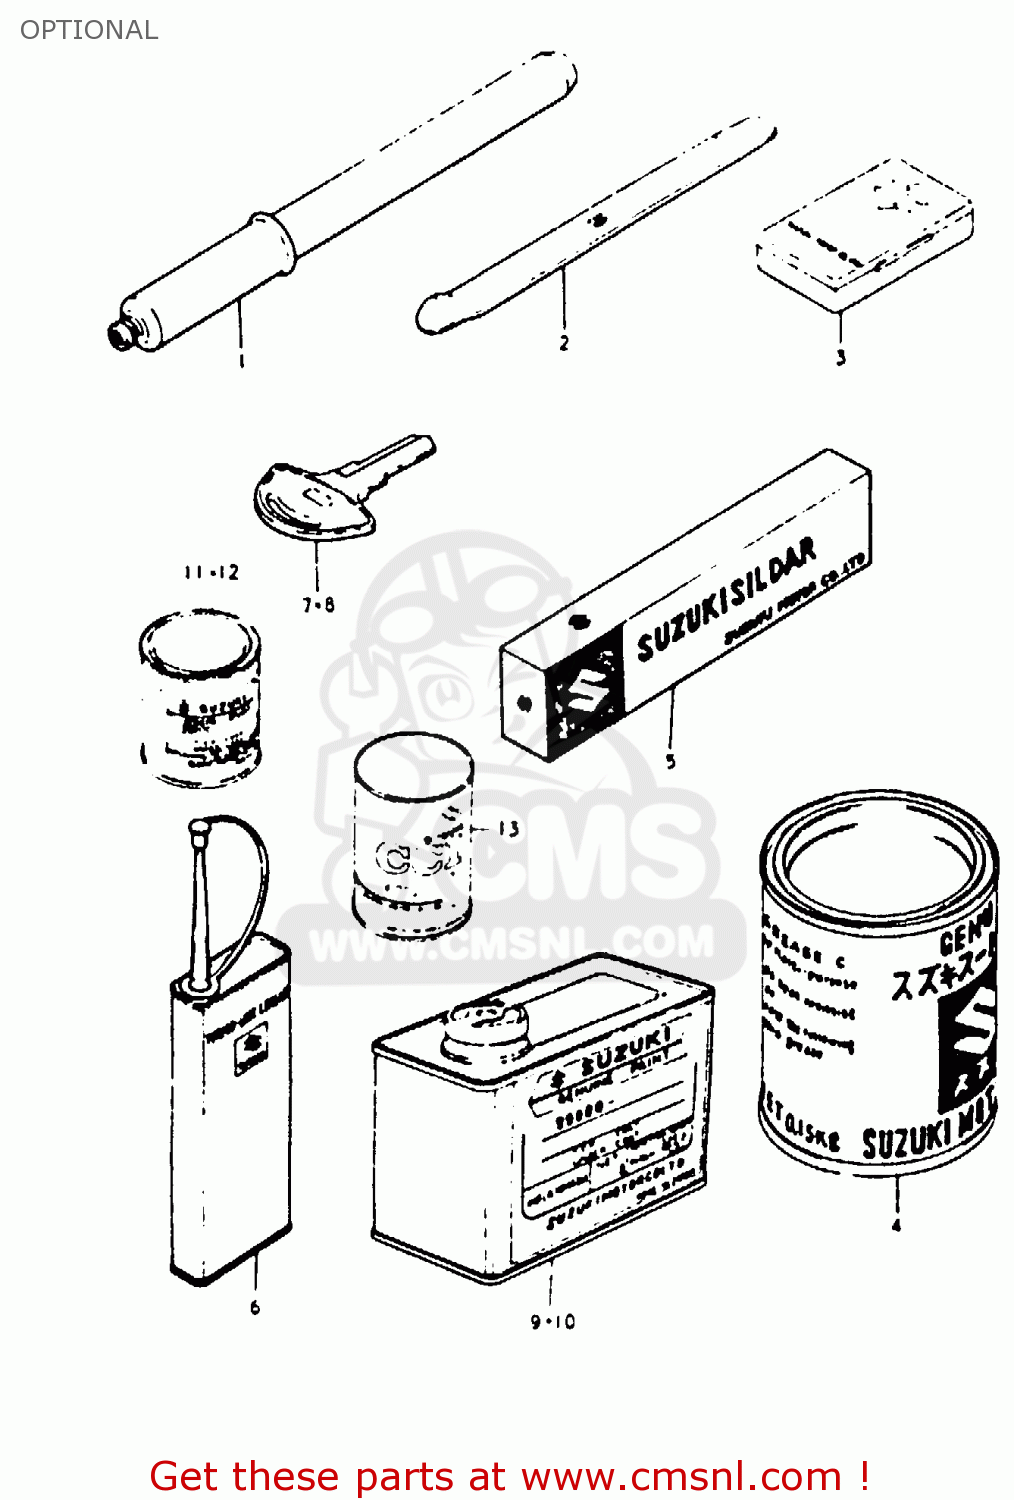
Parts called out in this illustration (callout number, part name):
1	INFLATOR, AIR
2	LEVER,TIRE
3	TUBE REPARING TOOL
4	GREASE(C)EP2 LITHIUM 150G
5	GASKET, LIQUID
6	THREAD LOCK NO.1401 CLEAR 200G
8	KEY,BLANK
9	PAINT (BLACK)
10	PAINT (MARBLE PURE RED)
11	PAINT,BLACK
12	PAINT (MARBLE PURE RED)
13	CCI OIL
